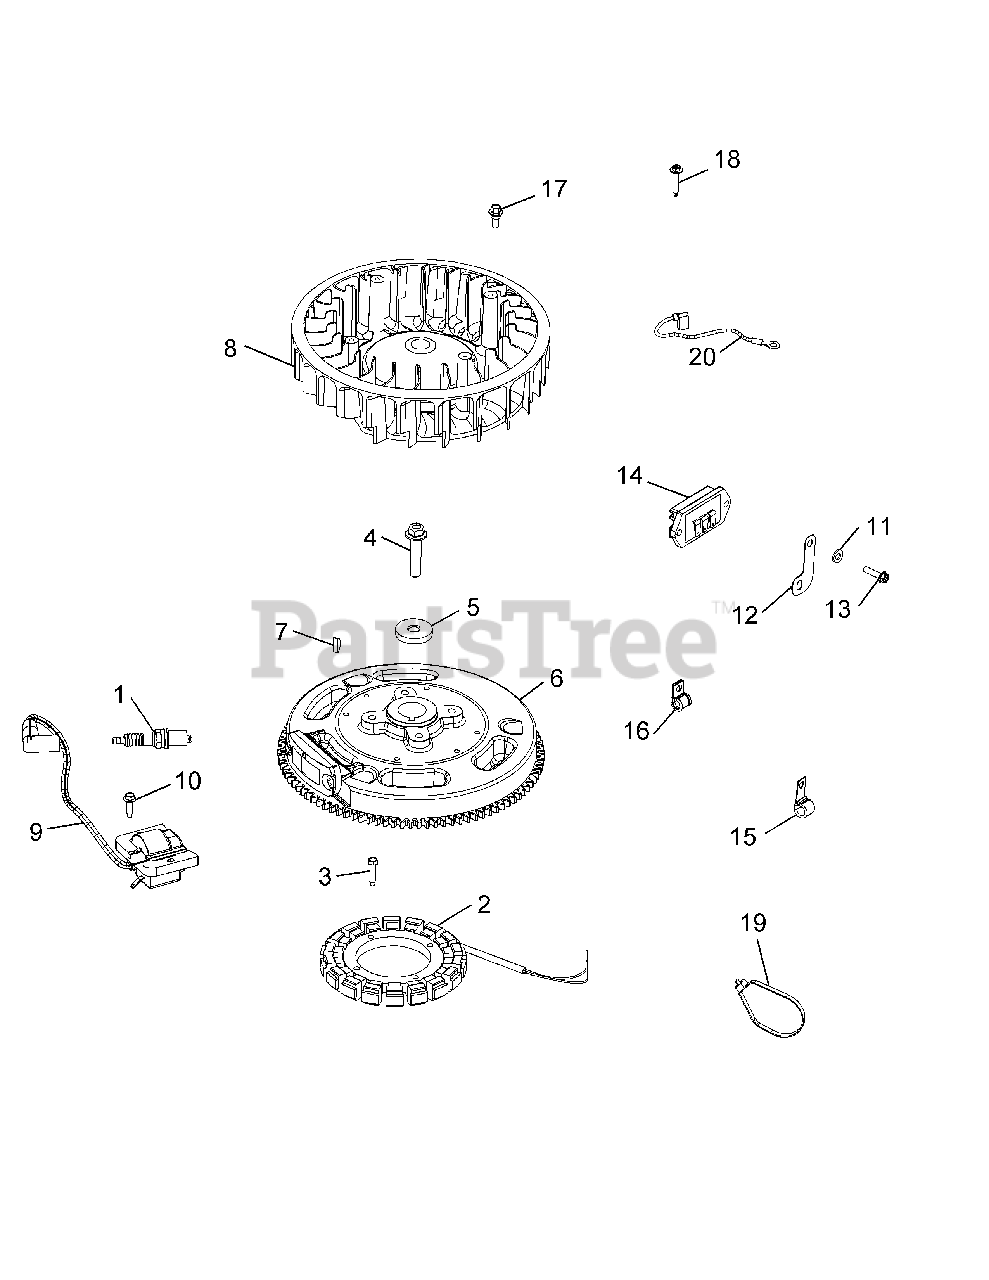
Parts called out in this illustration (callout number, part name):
2	15 Amp Stator Kit
3	Thread Forming Screw
4	Flange Screw, M10 x 1.5 x 45
5	Flat Washer, 13/32"
7	Key, 3/16 x 5/8
9	Ignition Module Kit
10	Thread Forming Screw
11	Flat Washer, 1/4
12	Ground Strap Bracket
13	Hi-Lo Hex Flange Screw
14	Rectifier Regulator
15	Cable Clip
17	Shoulder Bolt
18	Flange Screw, M4 x .7 x 25
